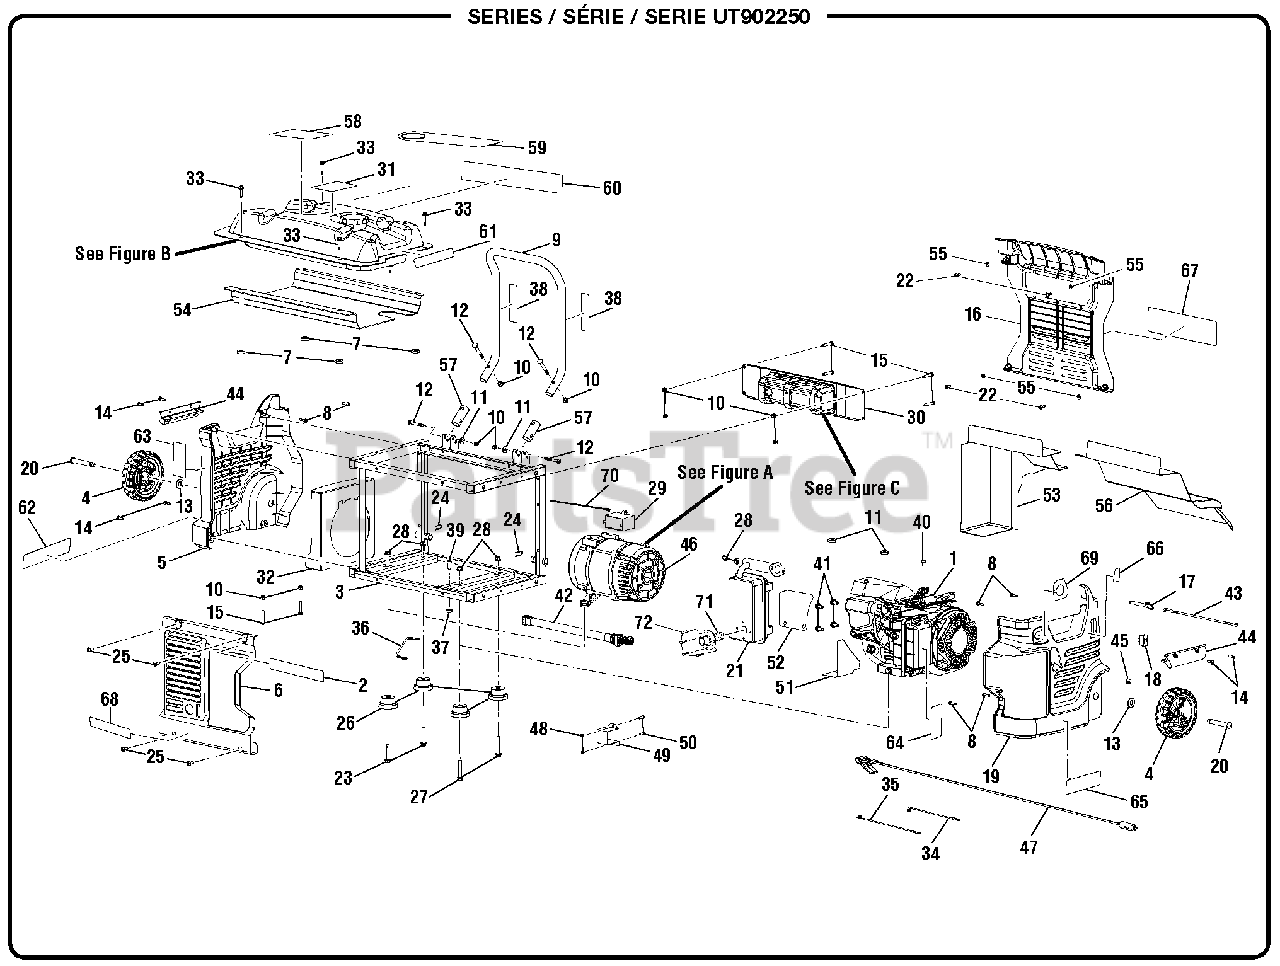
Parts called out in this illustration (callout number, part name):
2	Engine Lubricant Label
3	Frame Assembly
5	Panel Cover
6	Service Panel
7	Nylon Washer (D20 x D8 x 4.5t)
8	Screw (#9-18 x 20 mm)
9	Handle Assembly
10	Lock Nut (1/4-20)
11	Washer (1/4 in.)
12	Bolt (1/4-20 x 2 in., Hex Hd.)
13	Washer (1/2 in.)
14	Screw (12-14 x 15 mm)
15	Screw (1/4-20 x 1-3/4 in., T30 Torx Hd.)
16	Control Panel Cover
17	Release Pin
19	Outer Panel
20	Wheel Axle
21	Muffler Assembly
22	Screw (#9-18 x 15 mm)
23	Bolt (M8 x 45 mm, Hex Flange Hd.)
24	Axle Clip
25	Screw (1/4-20 x 1/2 in.)
26	Rubber Foot
27	Bolt (M8 x 50 mm)
28	Lock Nut (M8)
29	Capacitor
30	Control Panel Assembly
31	E85 Label
32	Intake Heat Shield
33	Screw (10-16 x 1 in.)
34	White Assembly Wire (18 Ga.)
35	Brown Assembly Wire (18 Ga.)
36	Ground Assembly Wire
37	Flange Nut (15/16-18)
38	Handle Warning Label
39	Bolt (5/16-18 x 3/4 in.)
40	Bolt (M6 x 10 mm)
41	Bolt (5/16-24 x 5/8 in.)
42	Pigtail (Male Connector w/Wire)
43	Lanyard (3/16 in.)
44	Handle Grip
45	Recoil Rope Guide
46	Generator Head Assembly
47	Battery Cable Assembly
48	Hex Nut (M5)
49	Capacitor Holder
50	Bolt (M5 x 16 mm, Pan Hd.)
51	Heat Shield (Engine Air Inlet)
52	Heat Shield (Separator)
53	Heat Shield (Muffler)
54	Heat Shield (Under Fuel Tank)
56	Heat Shield
58	CPSC Label
59	Engine Warning Hangtag
60	Danger Label
61	Fire Danger Label
62	Ground Warning Label
63	Hot Surface Label
64	Starting Instructions Label
65	Data Plate
66	Engine Switch Label
67	Logo Label
68	Combustion Label
69	Fuel Valve Label
70	Cable Tie
71	Spark Arrestor Screen
72	Screw (M3.5 x 9.5 mm)
